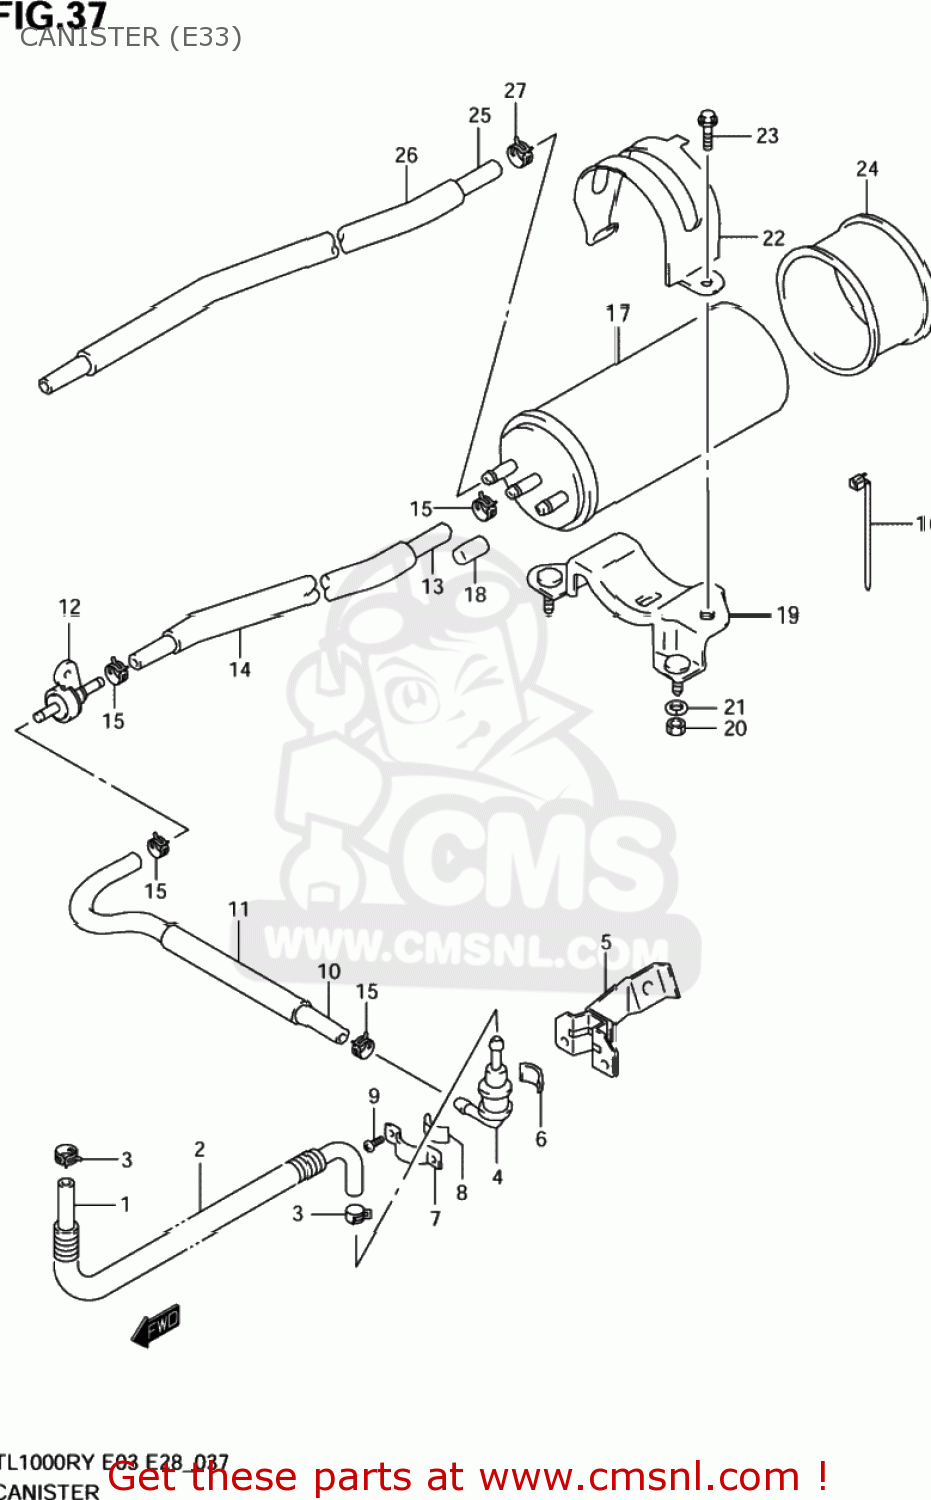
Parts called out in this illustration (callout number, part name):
1	HOSE,FUEL TANK & BREATHER
2	(CA) SPRING
3	CLIP
4	VALVE,FUEL TANK BREATHER
5	PLATE,FUEL TANK BREATHER VALVE
6	CUSHION
7	PLATE,FUEL TANK BREATHER NO.2
8	CUSHION
9	SCREW
10	HOSE(5.4X11.4X600)
11	PROTECTOR(14.5X15.5X600)
12	VALVE,2 WAY & BREATHER VALVE
13	HOSE(5.4X11.4X600)
14	PROTECTOR(14.5X15.5X600)
15	CLIP
16	CLAMP
17	CANISTER ASSY,CHARCOAL
18	CAP,OD:11.5
19	BRACKET,CANISTER
20	NUT
21	WASHER
22	HOLDER,CANISTER
23	SCREW 6X12
24	CUSHION,CANISTER
25	HOSE(5.4X11.4X1000)
26	HOSE
27	CLIP
